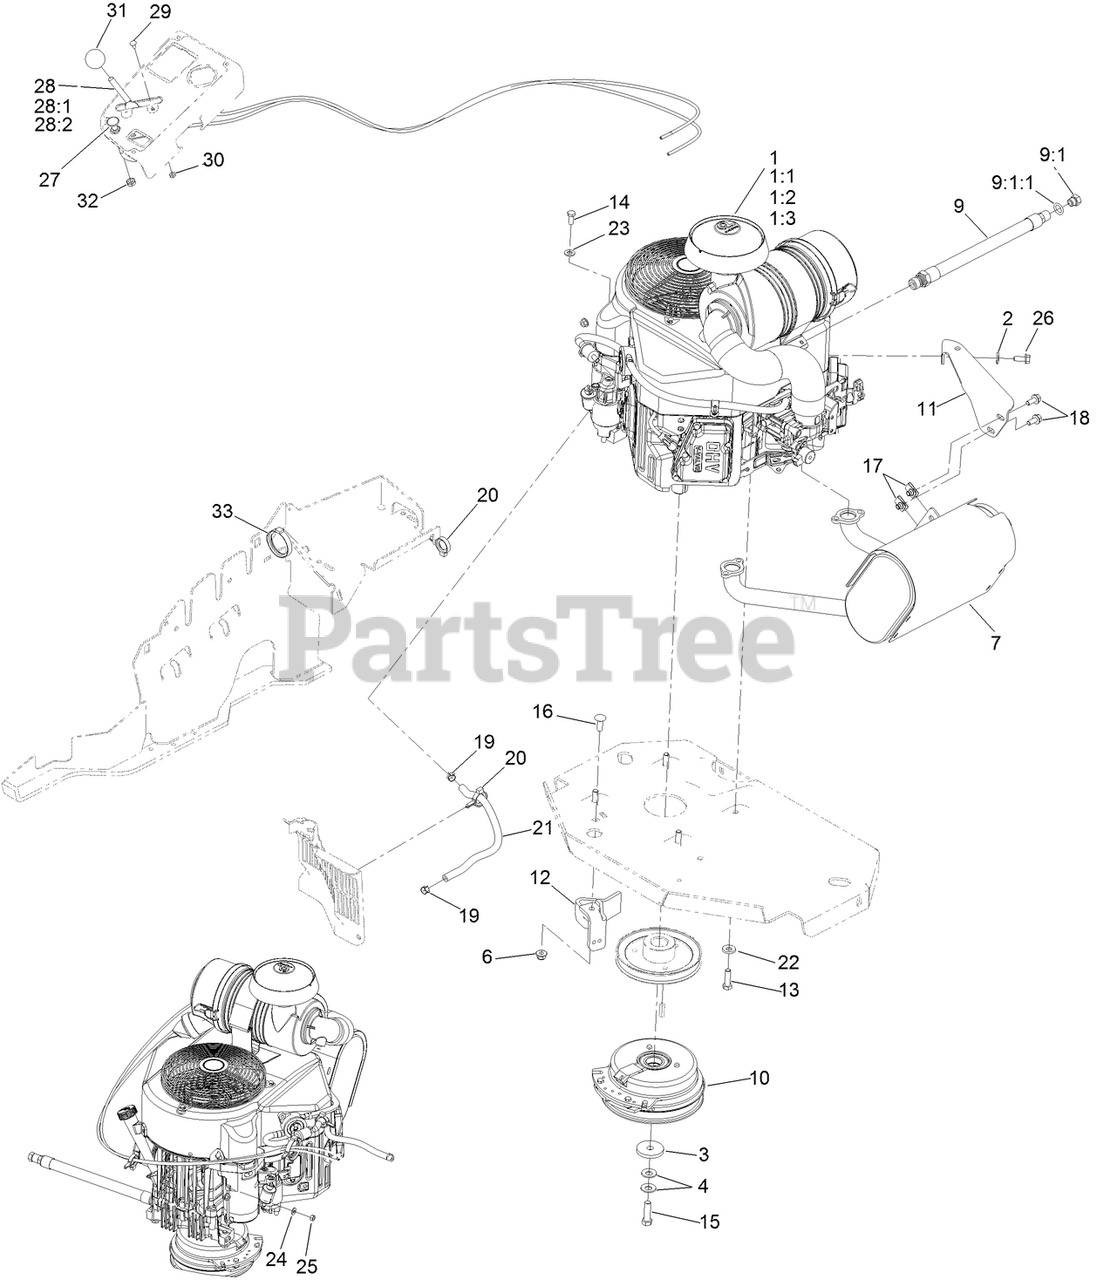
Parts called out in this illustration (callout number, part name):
1:1	KAWASAKI 49065-7007 ENGINE OIL FILTER
1:2	KAWASAKI 11013-7044 ENGINE AIR FILTER
1:3	KAWASAKI 11013-7045 SAFETY FILTER
2	WASHER-SPRING
3	WASHER-CLUTCH
4	WASHER-SPRING
6	NUT-HF, NI
7	MUFFLER
9	ENGINE OIL DRAIN HOSE ASM
9:1	PLUG-HH
9:1:1	O-RING
10	CLUTCH KIT
11	BRACKET-MUFFLER
12	CLUTCH-ANCHOR
13	SCREW-HH
14	SCREW-HH
15	SCREW-HH, W/LOCTITE
16	SCREW-CARR
17	NUT-U
18	SCREW-HH
19	CLAMP-HOSE
20	CLAMP-HOSE
21	HOSE-FUEL
22	WASHER-BELLEVILLE
23	WASHER-PLAIN
24	WASHER-FLAT
25	NUT-HEX
26	SCREW-HHF
27	CONTROL-CHOKE
28	THROTTLE CONTROL ASM
28:1	LEVER-THROTTLE
29	BOLT-CARR
30	NUT-LOCK, NI
31	KNOB-BALL
32	NUT-HJ
33	CLAMP-HARNESS
